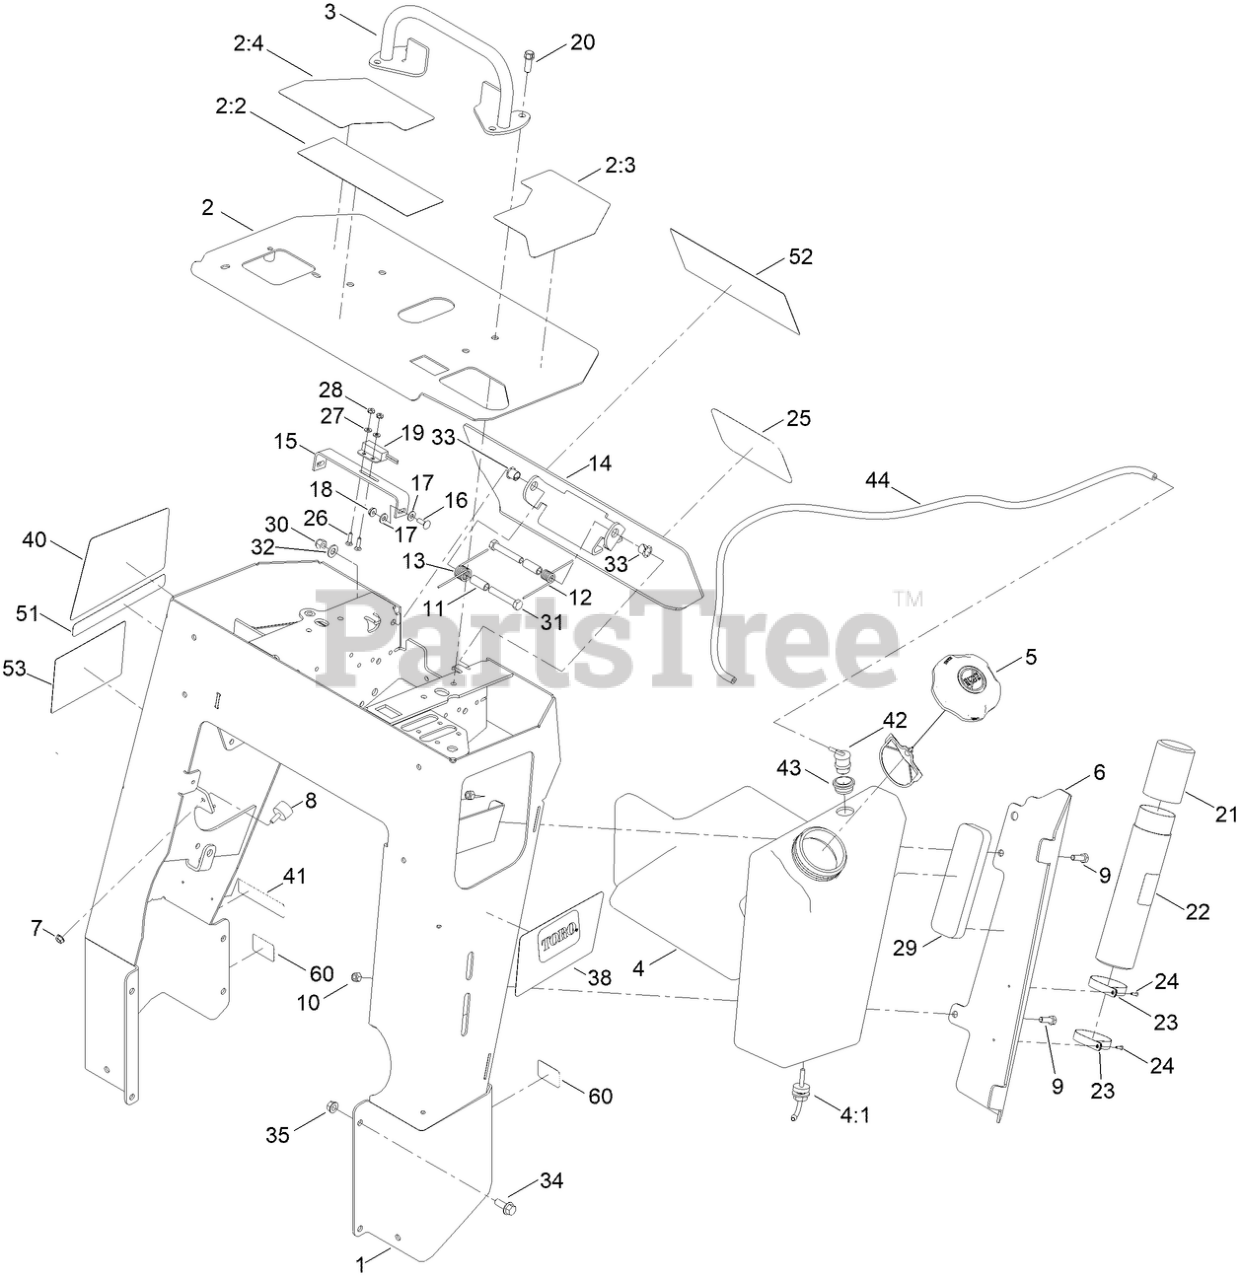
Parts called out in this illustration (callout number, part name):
2	CONTROL PANEL ASM
2:2	DECAL-WARNING
2:3	DECAL-CONSOLE, LH
2:4	DECAL-CONSOLE, RH
3	BAR-REFERENCE
4	TANK-FUEL
4:1	FITTING-FUEL, BULKHEAD
5	CAP-FUEL, RATCHETING
6	BRACKET-COVER, TANK
7	NUT-HF
8	BUMPER
9	SCREW-HH
10	NUT-LOCK, NI
11	SPACER-SPRING
12	SPRING-TORSION, LH
13	SPRING-TORSION, RH
14	PLATE-REVERSE
15	PLATE-SWITCH
16	BOLT-CARR
17	WASHER-FLAT
18	NUT-KEPS
19	SWITCH-PROXIMITY
20	SCREW-TAPTITE
21	CAP-HOUSING
22	TUBE-MANUAL
23	CLAMP-R
24	RIVET-POP
26	SCREW-CARR
27	WASHER-FLAT
28	NUT-KEPS
29	PAD-FOAM
30	NUT-LOCK, NI
31	SCREW-HH
32	WASHER-FLAT
33	BUSHING-NYLINER
34	SCREW-HHF
35	NUT-FLANGE
38	DECAL-SIDE, LH
40	DECAL-SIDE, RH
41	DECAL-ARRESTOR, SPARK
42	VALVE-VENT, FUEL
43	GROMMET
44	HOSE-VENT, TANK
51	DECAL-INTELLISWEEP
52	DECAL-S8HSW4X10
53	DECAL-SRVSW4X6
60	DECAL-LIFT, TIE DOWN
